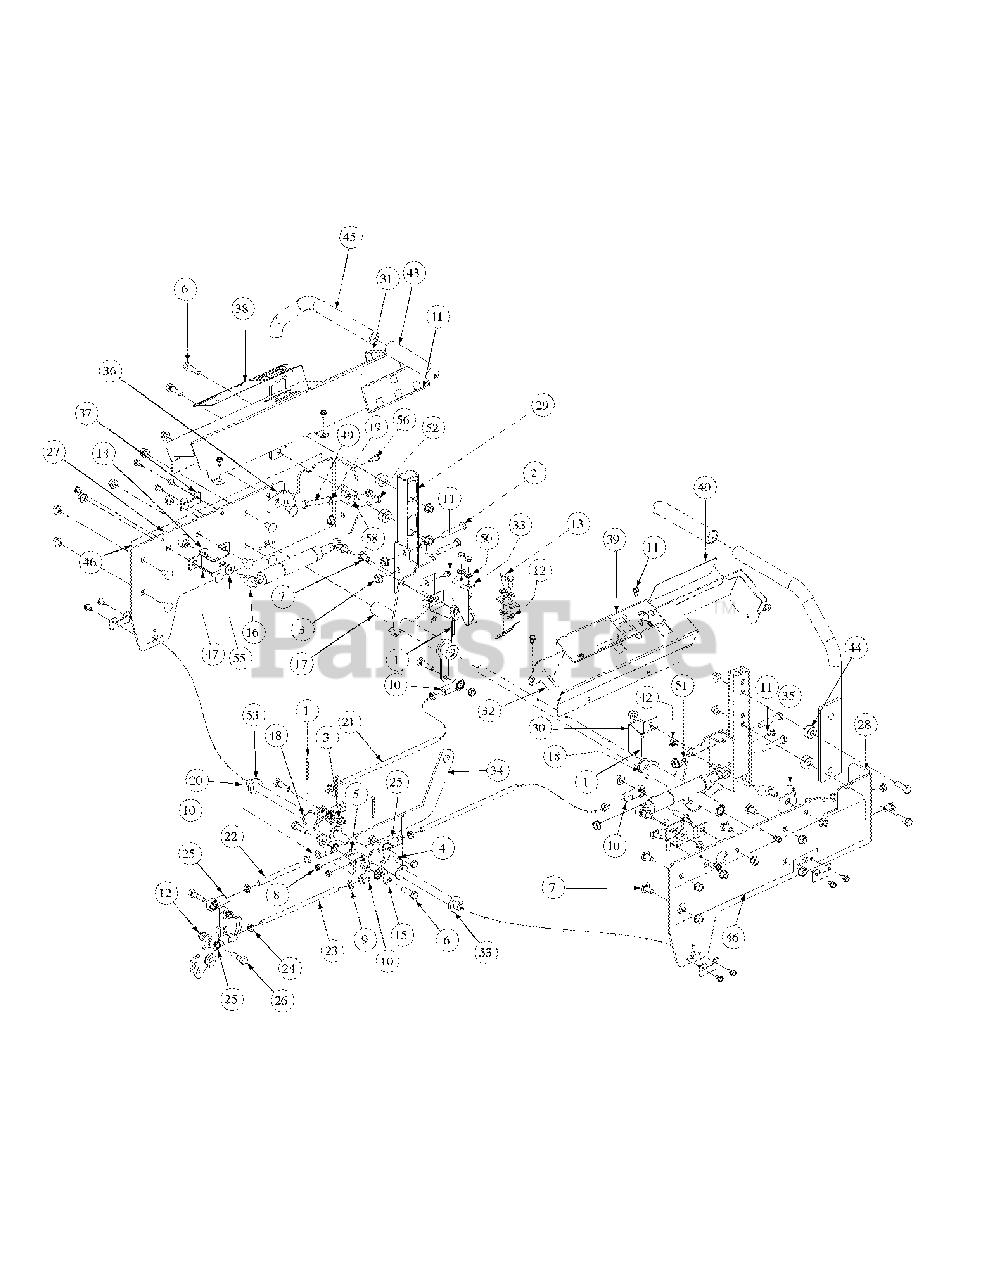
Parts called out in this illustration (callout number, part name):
1	Cotter Pin .125 Dia x 1.0
2	Hex Cap Screw, 3/8-16, 2.5
3	Hex Nut, 3/8-16, Lock Flange
4	Grease Fitting, 1/4-28 x 3/16
5	Hex Cap Screw, 1/4-20, .75
6	Hex Cap Screw, 3/8-16, 1.25
7	Carriage Bolt, 3/8-16 x .75
8	Lock Hex Nut, 1/4-20
9	Hex Jam Nut, 3/8-24
10	B/Joint, 3/8-24, Right Hand Female
11	Screw, TT, 1/4-20, 0.5, Hex Index Washer
12	Nut, Lock, HexFlange, 5/16-18
13	Hex, Cap Screw, 5/16-18 x 3/4
14	Belle Washer, .325 x .930 x .045
15	Belle Crank Assembly, includes:
15	Bushing
16	Cylinder Return to Neutral
17	Hub Assy, Control LH Bearing
18	Hub Assy, Control RH Bearing
19	Nut, 3/8-16, Jam
20	Shaft Mounting Belle Crank
21	Rod Connector 3/8 OD x 10.125
22	Rod Connector, 3/8 OD x 4.28 LG LH
23	Rod Connector, 3/8 OD x 8.06 LG RH
24	Nut, 3/8-24, Jam, LH Third
25	B/Joint, 3/8-24, LH Female
26	Screw, Shoulder Control Rod
27	Side Panel, Control, Left
28	Side Panel, Control, Right
29	Mounting Handle
30	Lever, Safety Switch
31	Control Panel, LH
32	Control Panel, RH
33	Switch Mounting Bracket, Lapbar
34	Link Mounting Control Shaft, Bracket
37	Holder Shaft, Park Brake
38	Decal , Warning & Throttle
39	Decal, Warning & Key Switch
40	Decal Right Hand Control
41	Decal, Left Hand Control
42	Nut, Hex, Center Lock, M8 x 1.2
44	Spacer, .406 ID x 1.00 OD x .38
45	Lapbar Handle, One Position
46	Side Label, CCC
47	Bracket Assembly, Mount Dampener
48	Flat Washer, 5/8 Nylon
49	HHCS, 3/8-16, 3.00
50	Flat Washer, 5/16
51	Grease Fitting, 90°, 1/4-28
52	HHCS, 5/16-18 x 1.0
53	Shaft Collar, .625 ID, 1.00 OD, .438 Lg
54	U-Nut, 3/8-16 x .75
55	External Lock Washer
56	Screw, TT, 1/4-20, 0.75, Hex Index Washer
